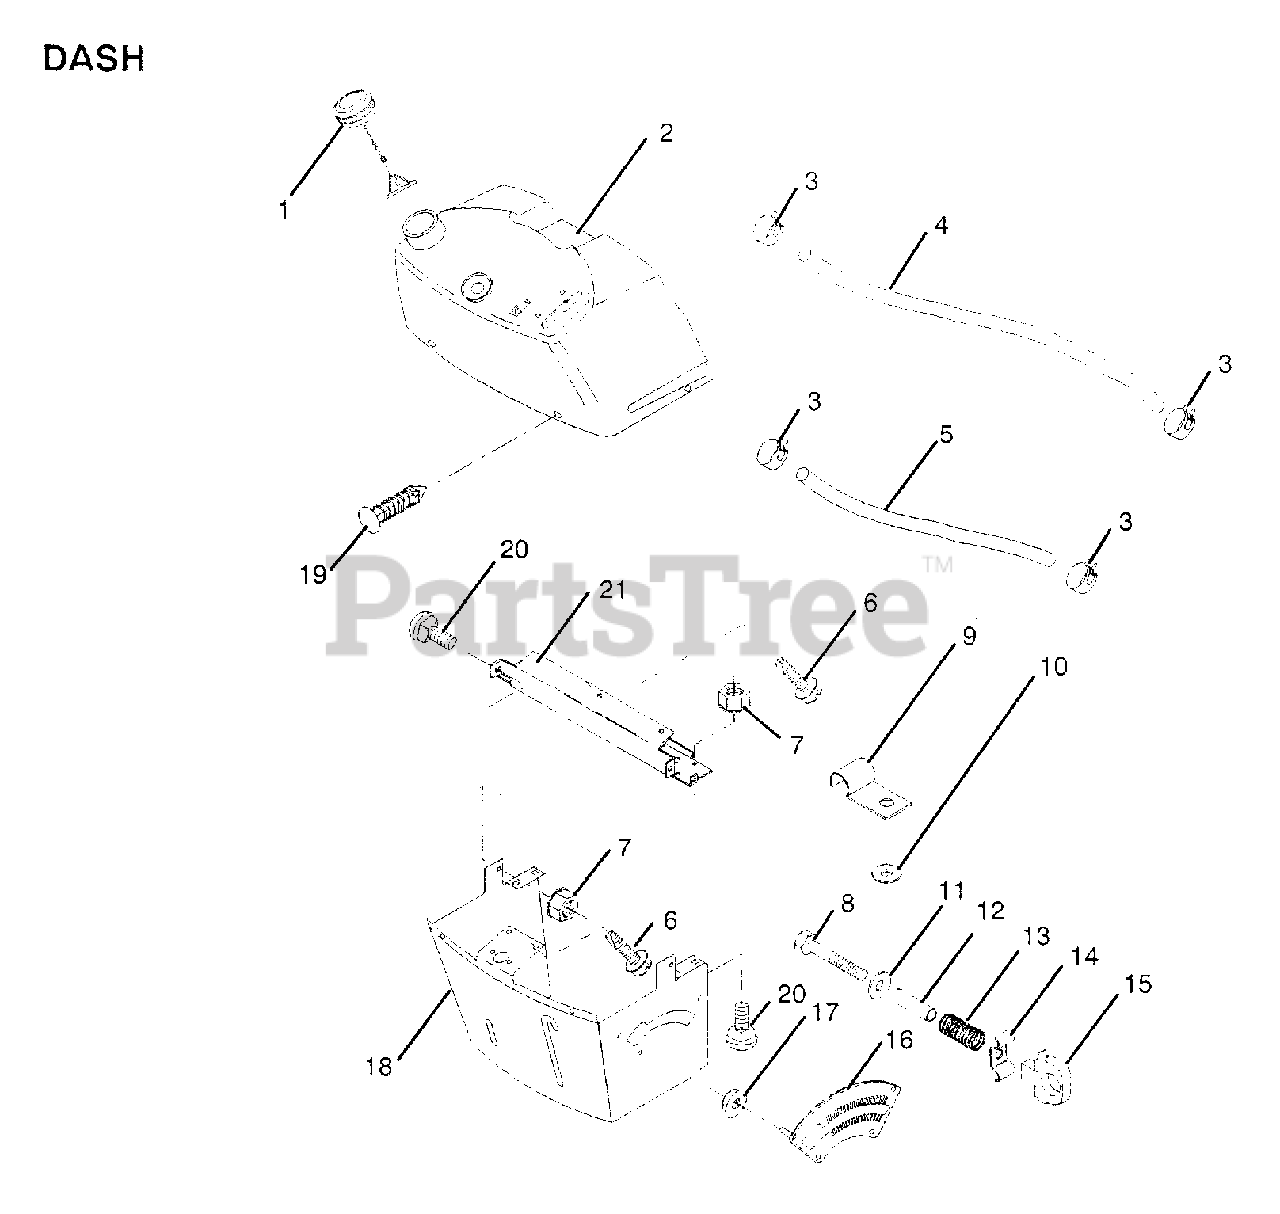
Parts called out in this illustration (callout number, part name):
3	HOSE CLAMP
4	FUEL LINE T
7	NUT
8	BOLT
9	CLIP T
10	WASHER PM
11	WASHER
12	SPACER SPLIT
13	SPRING T
14	HEIGHT ADJ
15	KNOB
16	ADJUSTER QUAD
17	NUT
18	SUPPORT DASH
19	SNAP
20	BOLT
21	"BRAKE,CROSS"
